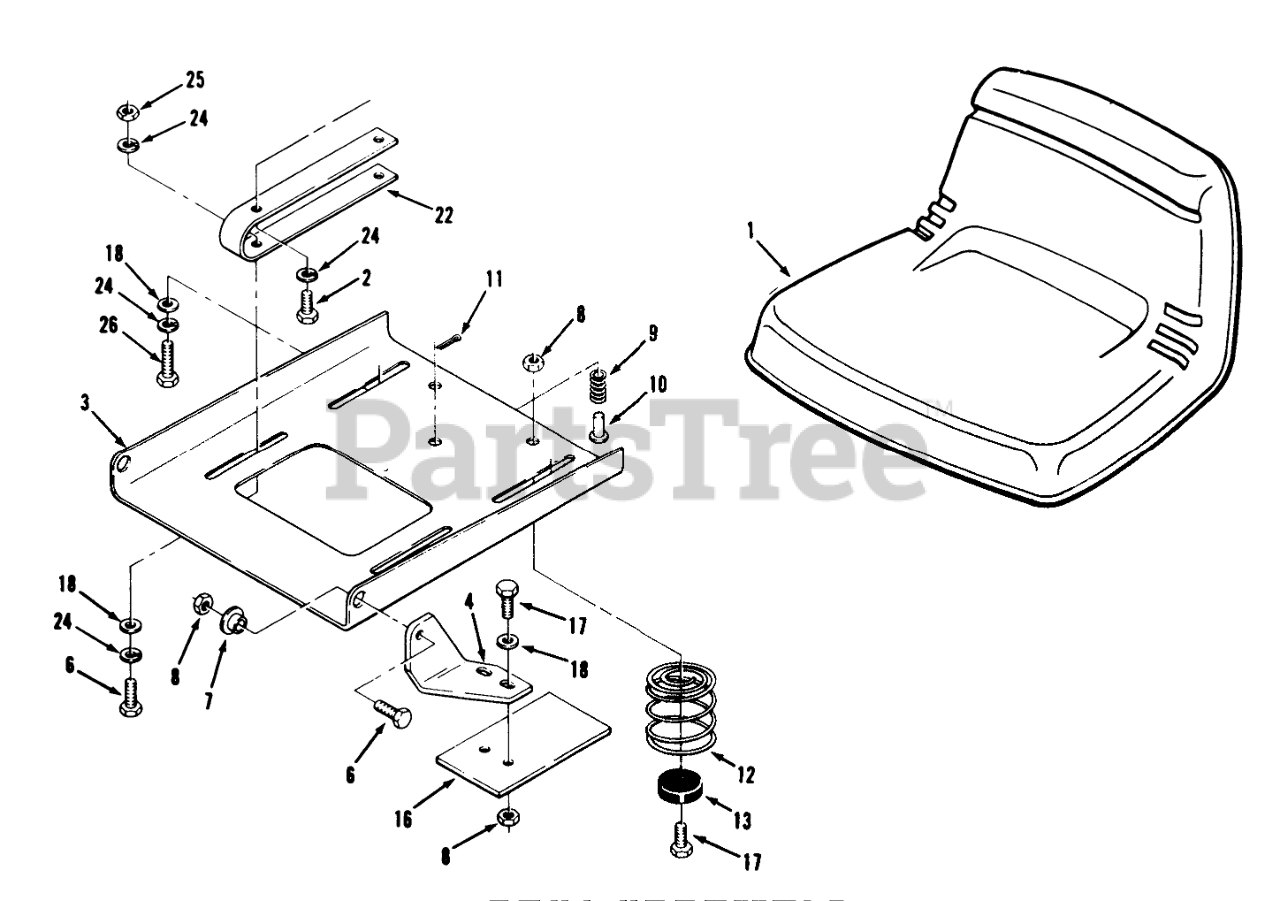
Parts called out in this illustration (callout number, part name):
1	SEAT V-410
2	SCREW-HH
3	PLATE-SEAT PIVOT B
4	BRACKET-PIVOT L.H B
6	SCREW-HH
7	BUSHING
8	NUT-LOCK, NI
9	SPRING-SEAT SWITCH
11	PIN-COTTER
12	Spring-Lifter
13	BUMPER
16	PLATE R
17	SCREW-HH
18	WASHER-PLAIN
22	SPRING-SEAT B
24	WASHER-LOCK
25	NUT-HEX
26	SCREW-HH
